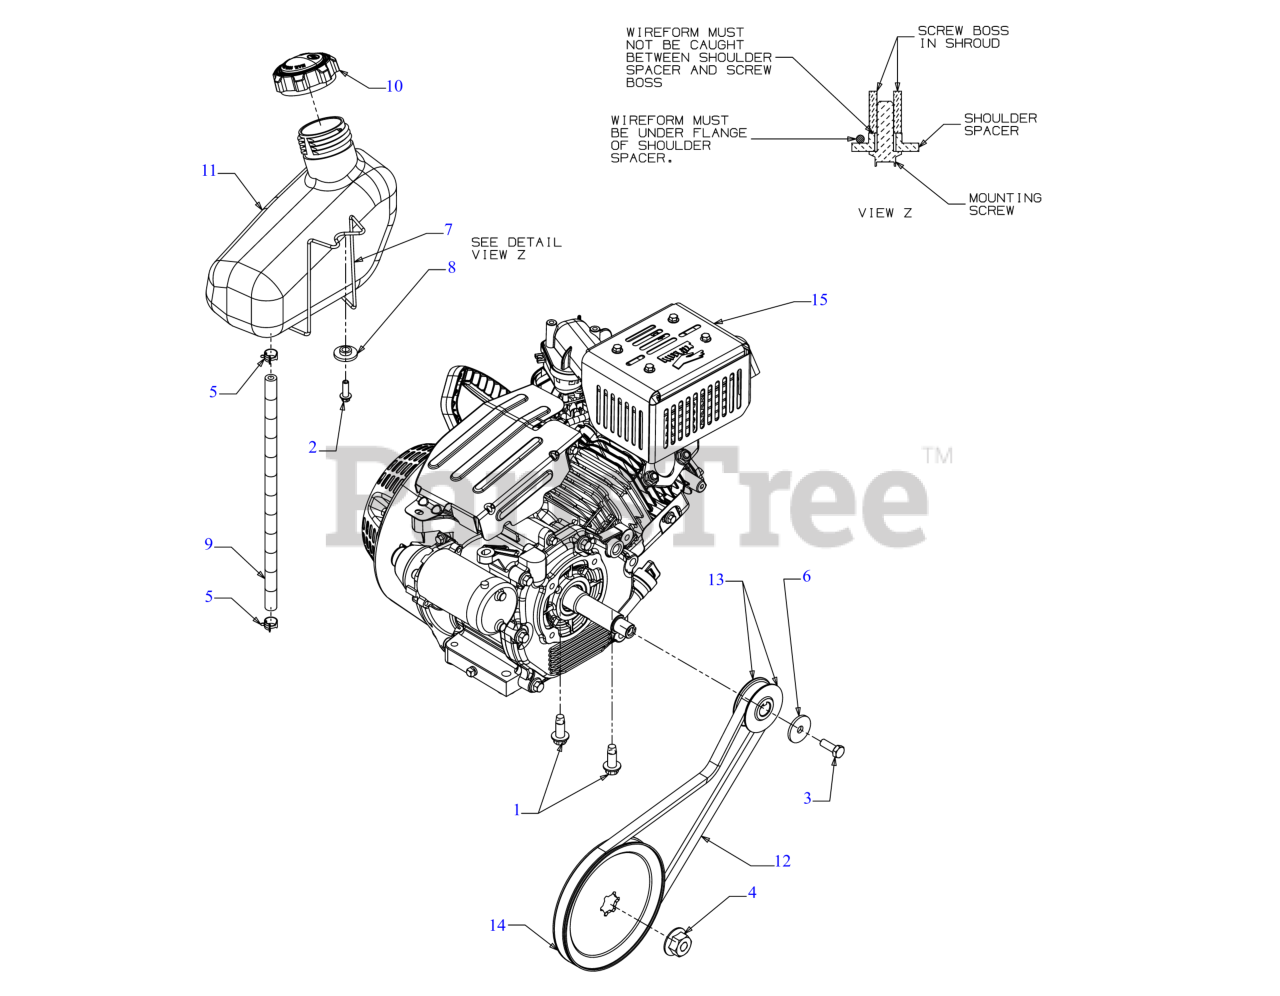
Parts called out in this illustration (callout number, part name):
1	SCREW 3/8-16 x 1
2	SCREW 1/4 x .750
3	SCREW 5/16-24 x .875 GR5
4	FLANGE NUT W/HUB
5	HOSE CLAMP 1/20
6	WASHER-5/16 x 1.25X 1.27
7	FUEL TANK WIRE SUPPORT
8	SHOULDER SPACER
9	FUEL HOSE LOW PERMEATION 16"
10	FUEL CAP
11	FUEL TANK (2 QT)
12	V-BELT .500 x 35.00LG
12	Cub Cadet AUGER BELT
12	Genuine Factory Parts AUGER BELT
13	HALF PULLEY
13	FLAT WASHER
14	AUGER PULLEY
15	COMPLETE ENGINE 123cc
